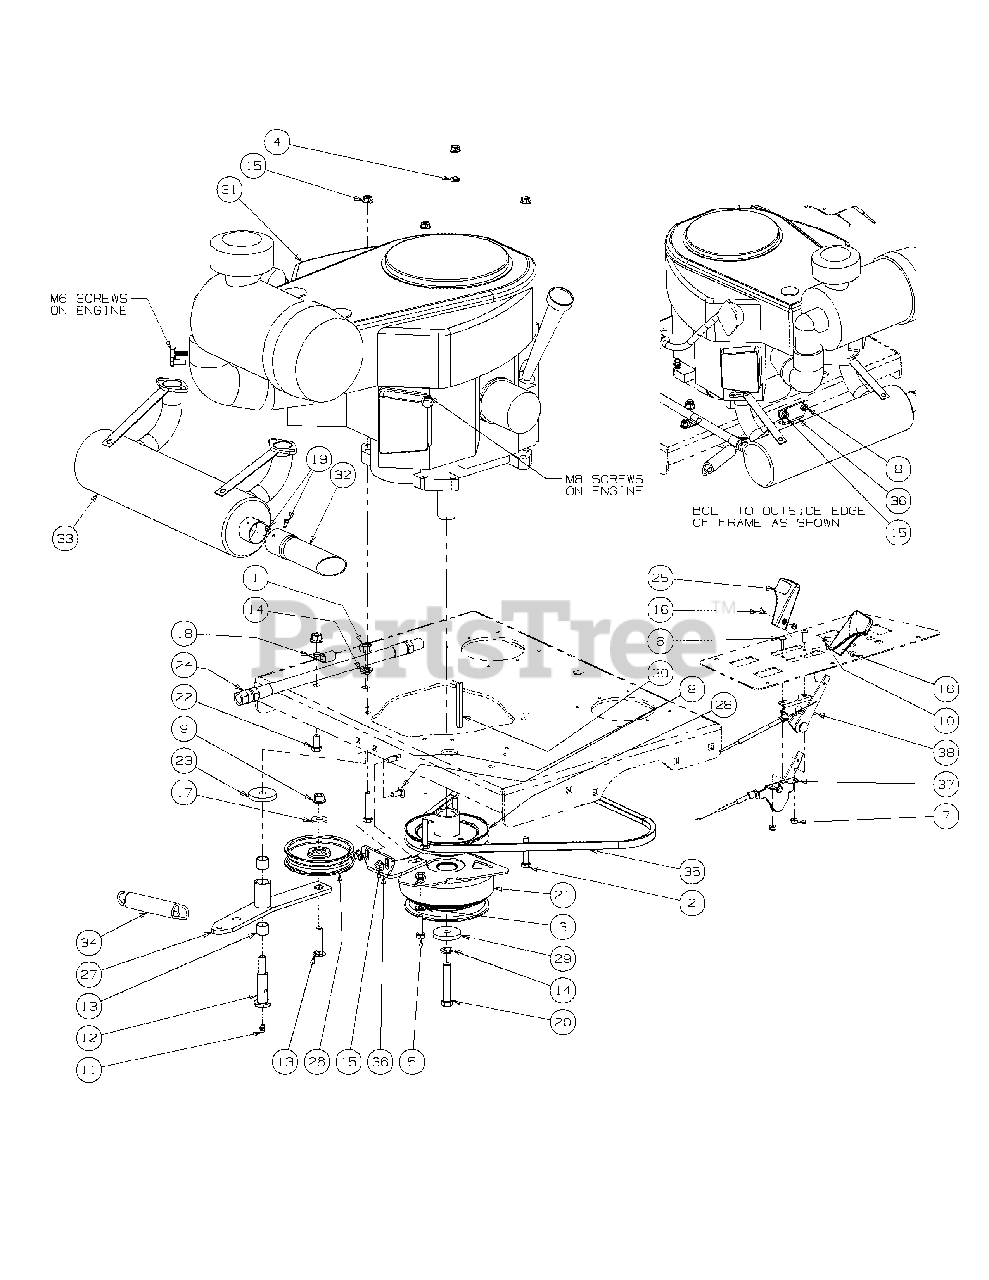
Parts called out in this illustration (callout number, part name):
1	Hex Nut, 7/16-14
2	HHCS, 5/16-18, 1-3/4
3	Flat Washer, 5/16
4	Flat Washer, 5/16
5	HHCS, 5/16-18 x 1-1/4
6	Round Hd. Machine Screw, 10-32 x 3/4
7	Lock Nut, Nylon Insert, 10-32
8	Carriage Bolt, 5/16-18 x .75
9	Flange Lock, Hex Nut, 3/8-16
10	Nut Washer, W/Star, 8-32
11	Grease Fitting, 1/4-28 x 3/16
12	Shoulder Screw, 7/16-14
13	Hex Carriage Screw, 3/8-16, 1.75
14	Lock Washer, 7/16
15	Hexflange Lock Nut, 5/16-18
16	Machine Screw, 8-32, .375
17	Flat Washer, .406 ID, 1.0 OD, .105
18	Clip, Heat Shield Cable
19	Screw, #8-32 x 0.375
20	Capscrew, 7/16-20 x 2.50
21	Clutch Brake, 1.125 ID
22	Hex Cap Screw, 3/8-16, .750
23	Flat Washer, 7/16 ID x 1.75 OD x .25
24	Oil Drain Hose
25	Control Throttle Knob
26	Flat Pulley with Flanges
27	Engine Idler Arm
28	Pump Drive Pulley
29	Flat Washer, 7/16 ID x 1.75 OD x .25
30	Key, 1/4 x 1/4 x 3
31	25HP Twin Engine, Kawasaki
32	Muffler Accessory Exhaust Tube
33	Muffler Accessory, Kawasaki
34	Extension Spring, .98 OD x 5.00
35	Belt, A Section x 50.0
36	Retainer Clutch Assembly, Ogura
37	Throttle, Control Cable
38	Choke, Control Cable
